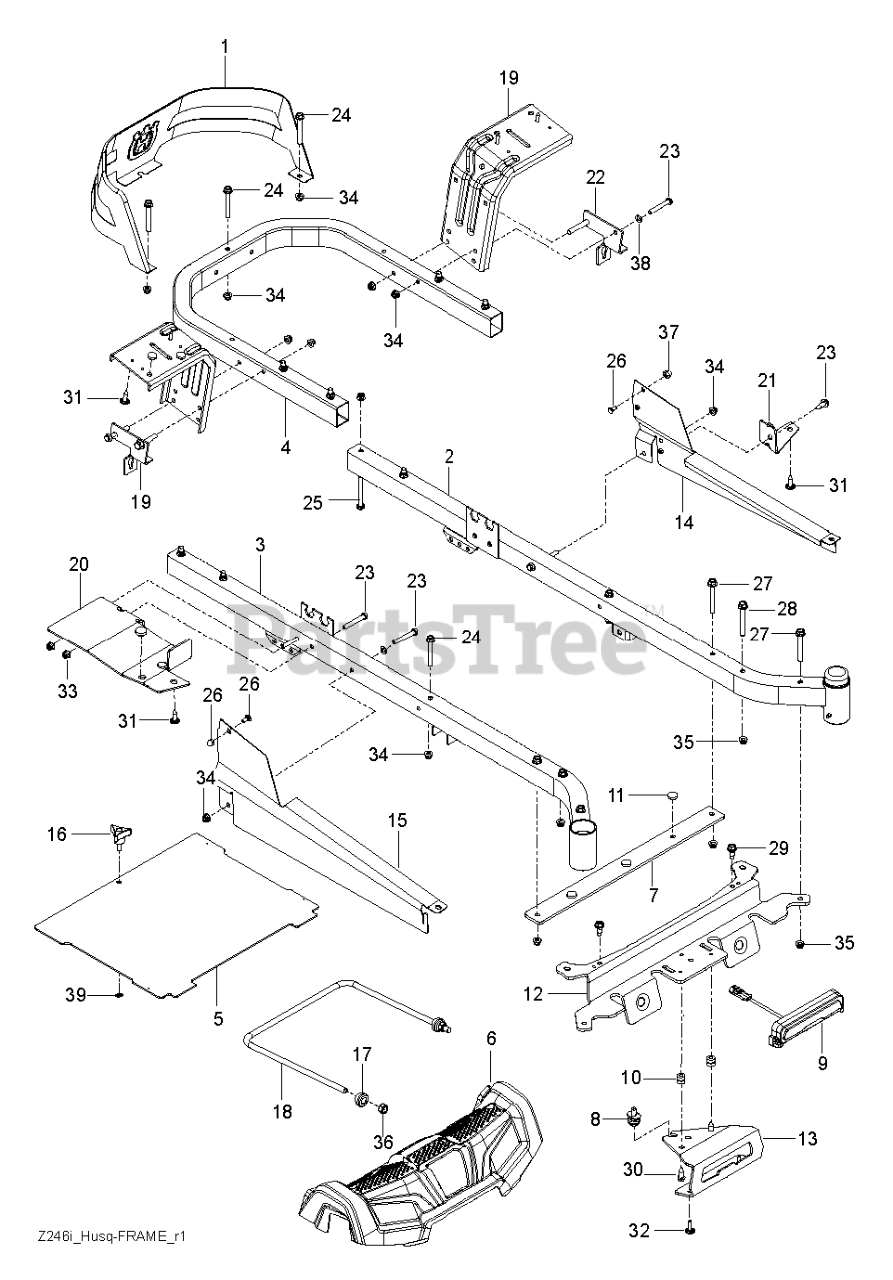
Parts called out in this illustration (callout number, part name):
1	GUARD.ENGINE.HUSQ.RZ.X498
2	FRAME, RT, ORANGE
3	FRAME, LT, ORANGE
4	TUBE.PNT.FRAME.RER.HUSQ.23".RZ
5	PLATE, FOOT W/DECALS RZ
6	FRONT COVER RZ REFRESH
7	FOOTREST.PLATE.SUPPORT.X431
8	SCREW.ADJ.ISOLATOR.BOLT.ASSY
9	LIGHT.ZTR.LED.ASM
10	GROMMET.RUBBER.PUSHIN
11	GROMMET.BUMPER
12	CROSS.PNT.MEMBER.BLK
13	BRACKET.SKIDPLTE.LED.RFRSHX417
14	COVER.RAIL.RH.RZ.X668
15	COVER.RAIL.LH.RZ.X668
16	KNOB W/STUD
17	BUSHING SPHERICAL SUSP. FRONT
18	LINK, FRONT SUSP.
19	FENDER.SUPPORT.PNT.X431
20	SUPPORT.PNT.RH.CONSOLE.FRONT
21	SUPPORT.PNT.LH.CONSOLE.FRONT
22	BRKT ROD.BYPASS.EZT.X431
23	BOLT.FIN HEX 5/16-18UNC X2 1/4
25	BOLT.HEX.FIN.3/8-16 X 3.GR5
26	BOLT.CARRIAGE.5/16-18.7/16
27	HHFS 3/8-16 X 3 GRD 5 ZD
28	BOLT SHOULDER,FLANGED,3/8-16X3
29	BOLT.5/16-18.THRD.ROLL.SHOULDR
30	BOLT.5/16-18.THRD.ROLL.SHOULDR
31	SCREW.#10 X 0.750.BOS
32	SCREW.#10 X 0.500
33	NUT LOCK HEX FLANGE 5/16-18
34	5/16-18 NYLOC FLANGE NUT
35	NUT 3/8-16 HEX FLG NYLOC ZD
36	7/16-14 HEX NUT W/NYL RING ZD
37	NUT ACORN,FLANGED,5/16-18
38	WASHER
39	WASHER 5/16"
